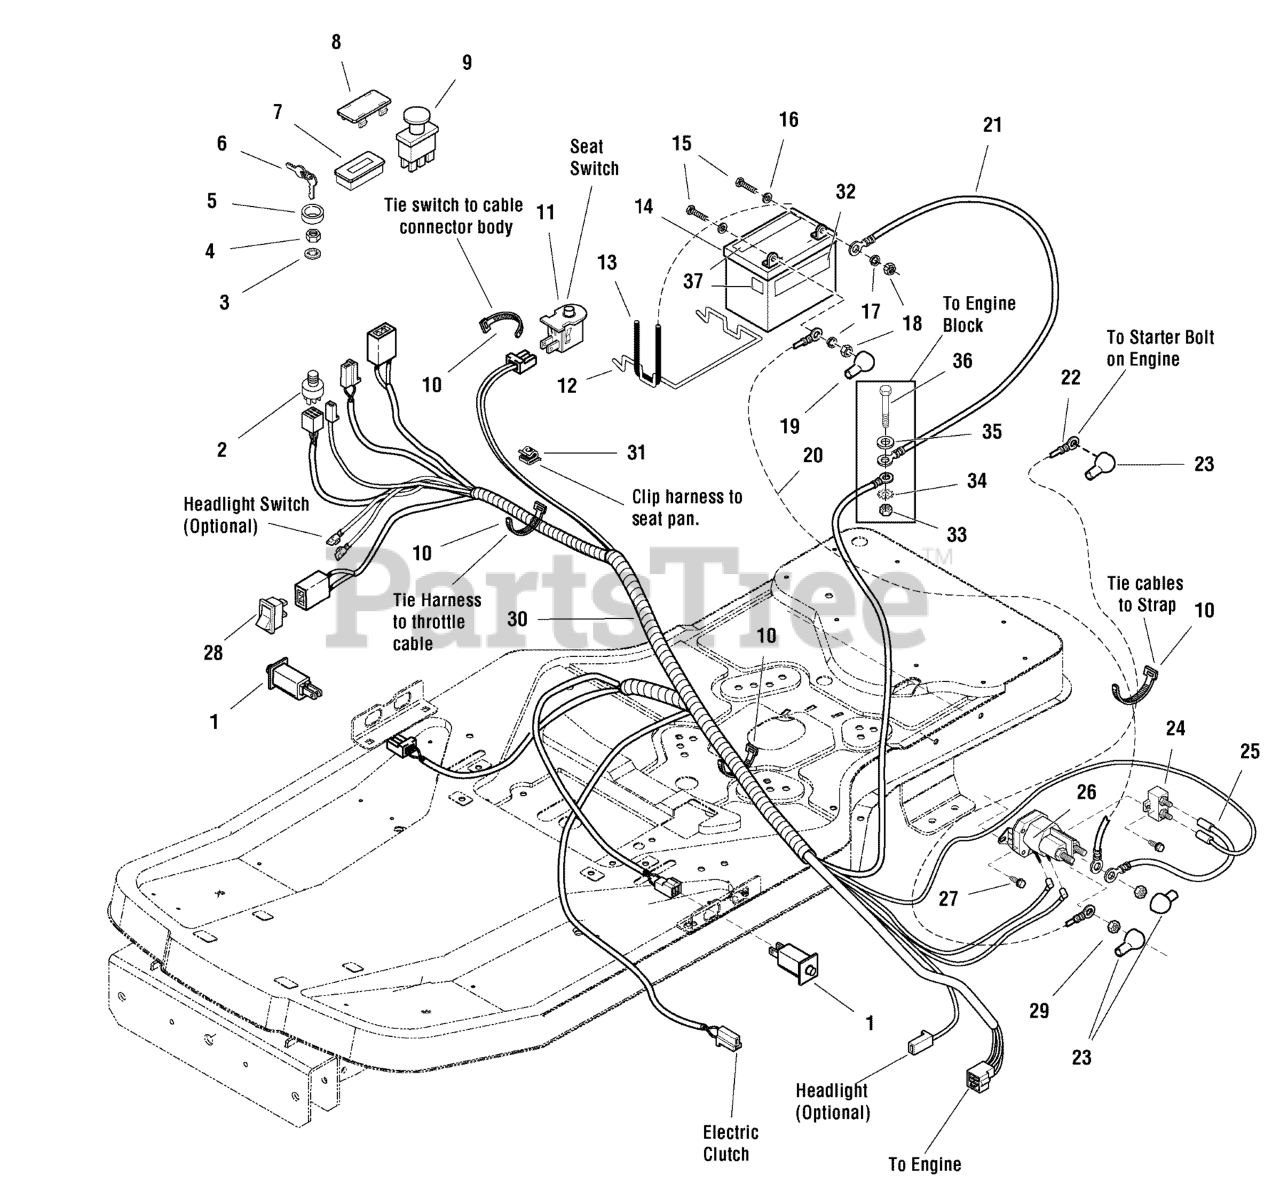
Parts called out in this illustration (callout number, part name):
1	SWITCH, Push Button
2	SWITCH ASSEMBLY, Ignition, 5/8-32 6 Pin Indak
3	LOCKWASHER, Internal Tooth, 5/8 Thin
4	NUT, Hex Flange, 5/8-32 IGN SW Die Cast
5	COVER, Ignition Switch
6	KEYS
7	HOUR METER, No Alarms
8	PLUG, Hole
9	SWITCH, PTO, Push/Pull
10	TIE, Self Locking, .184 WD 7.31 LG
11	SWITCH, Push Button
12	BRACE, Battery, .19 DIA Wire
13	STRAP, Black Rubber, .19 SQ 7.88 OD Battery
15	CAPSCREW, Hex Head, 1/4-20 x 3/4, G5
16	WASHER, 1/4, .27 ID x .62 OD x .05 THK
17	LOCKWASHER, Spring, 1/4
18	NUT, Hex, 1/4-20 NC-2B
19	BOOT, Insulator, Red PVC Warning
20	CABLE, # 6 x 10 LG, Red Two-Ring Terminals
21	CABLE, # 6 X 26 LG, Two-Ring Terminals
22	CABLE, # 6 x 15 LG, Two-Ring Terminals
23	COVER, Terminal Red PVC
24	BREAKER, Circuit, 12 Volt 20 AMP
25	WIRE, 12 Gauge, 7.9 LG
26	SOLENOID, Two Terminals, Trombetta
27	SCREW, Hex Washer Head Taptite, 1/4-20 x 1/2
28	SWITCH, Electric Height of Cut
29	NUT, Hex Keps, 5/16-24
30	HARNESS, Wiring
31	CABLE, Clip
32	DECAL, Danger Poison
33	NUT, Hex Whiz Lock Flange, 5/16-18
34	LOCKWASHER, External Tooth, 3/8
35	WASHER, 5/16
36	CAPSCREW, Hex Head, 5/16-18 x 2, G5
37	DECAL, Diehard
